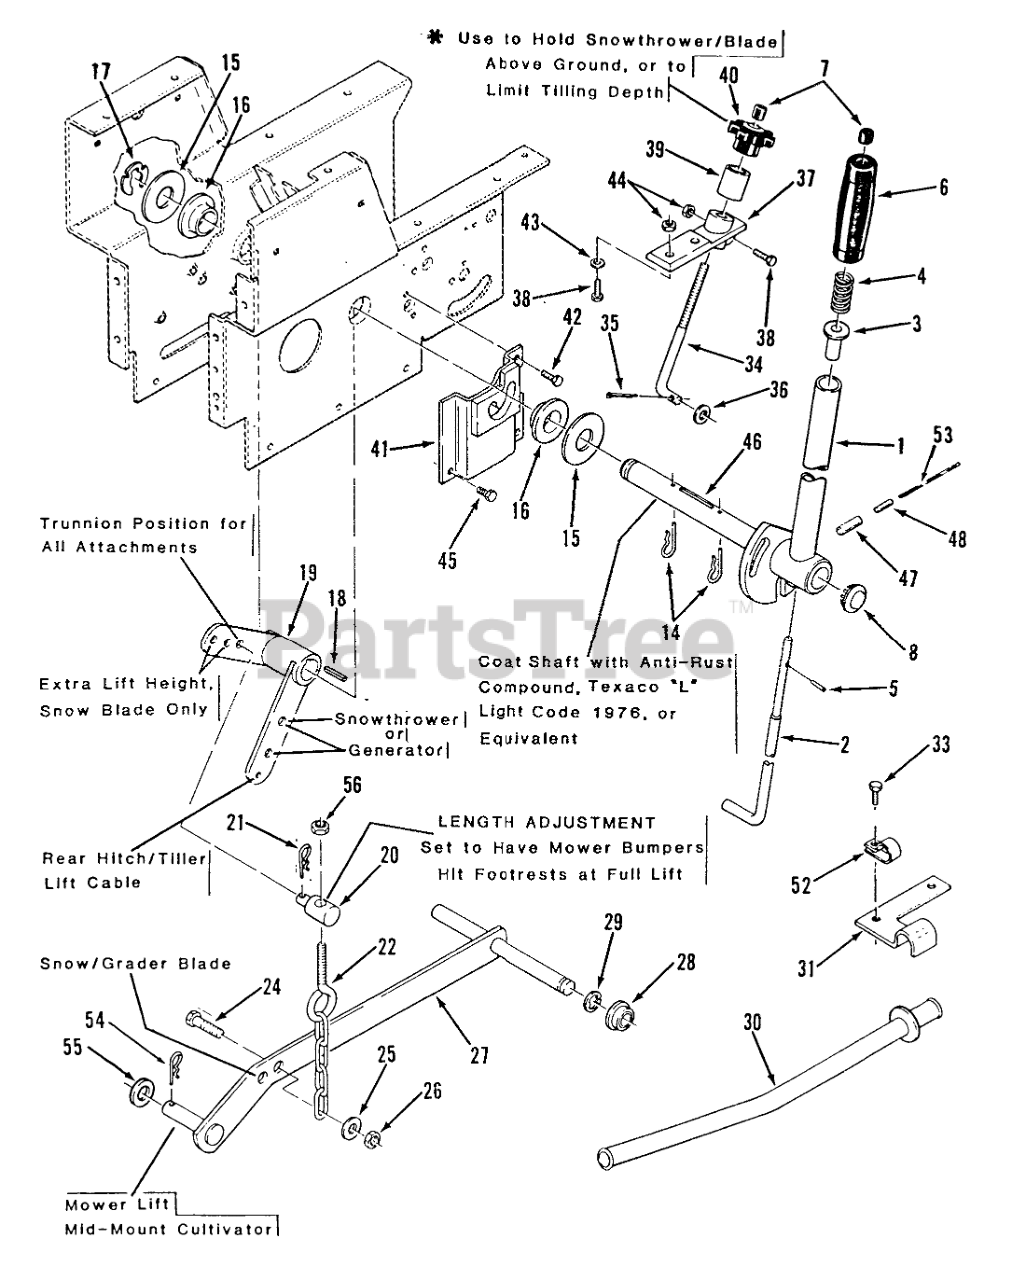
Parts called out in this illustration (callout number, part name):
1	Lift Lever (Includes Items 46, 47, 48)
2	ROD-LATCH LIFT
3	RETAINER-SPRING
4	SPRING-COMPRESSION
5	PIN-SPIROL
6	HANDGRIP
7	CAP-ROD, PLUNGER
8	PLUG
14	Pin-Cotter
15	WASHER
16	BEARING-FLANGE
17	Retainer
18	KEY-SQUARE
19	Bellcrank
20	TRUNNION-LIFT
21	Hairpin
22	CHAIN-LIFT
24	Bolt
25	WASHER 5/16 SAE
26	Nut
27	Bar-Lift
28	BUSHING
29	E Ring
30	TUBE ASSY COMPLET R
31	CLAMP-CONDUIT R
33	BOLT
34	ROD-HEIGHT CONTROL
35	Pop Rivet
36	Washer, 7/16
37	Casting
38	Bolt
39	Sleeve
40	KNOB-LIFT CONTROL
41	Latch Bracket
42	SCREW
43	WASHER 5/16 SAE
44	Nut
45	Bolt
46	SHAFT-LIFT LEVER
47	SPIROL PIN
48	Roll Pin
52	CLIP
53	Lock Wire
54	Hairpin Cotter
55	Washer
56	NUT
